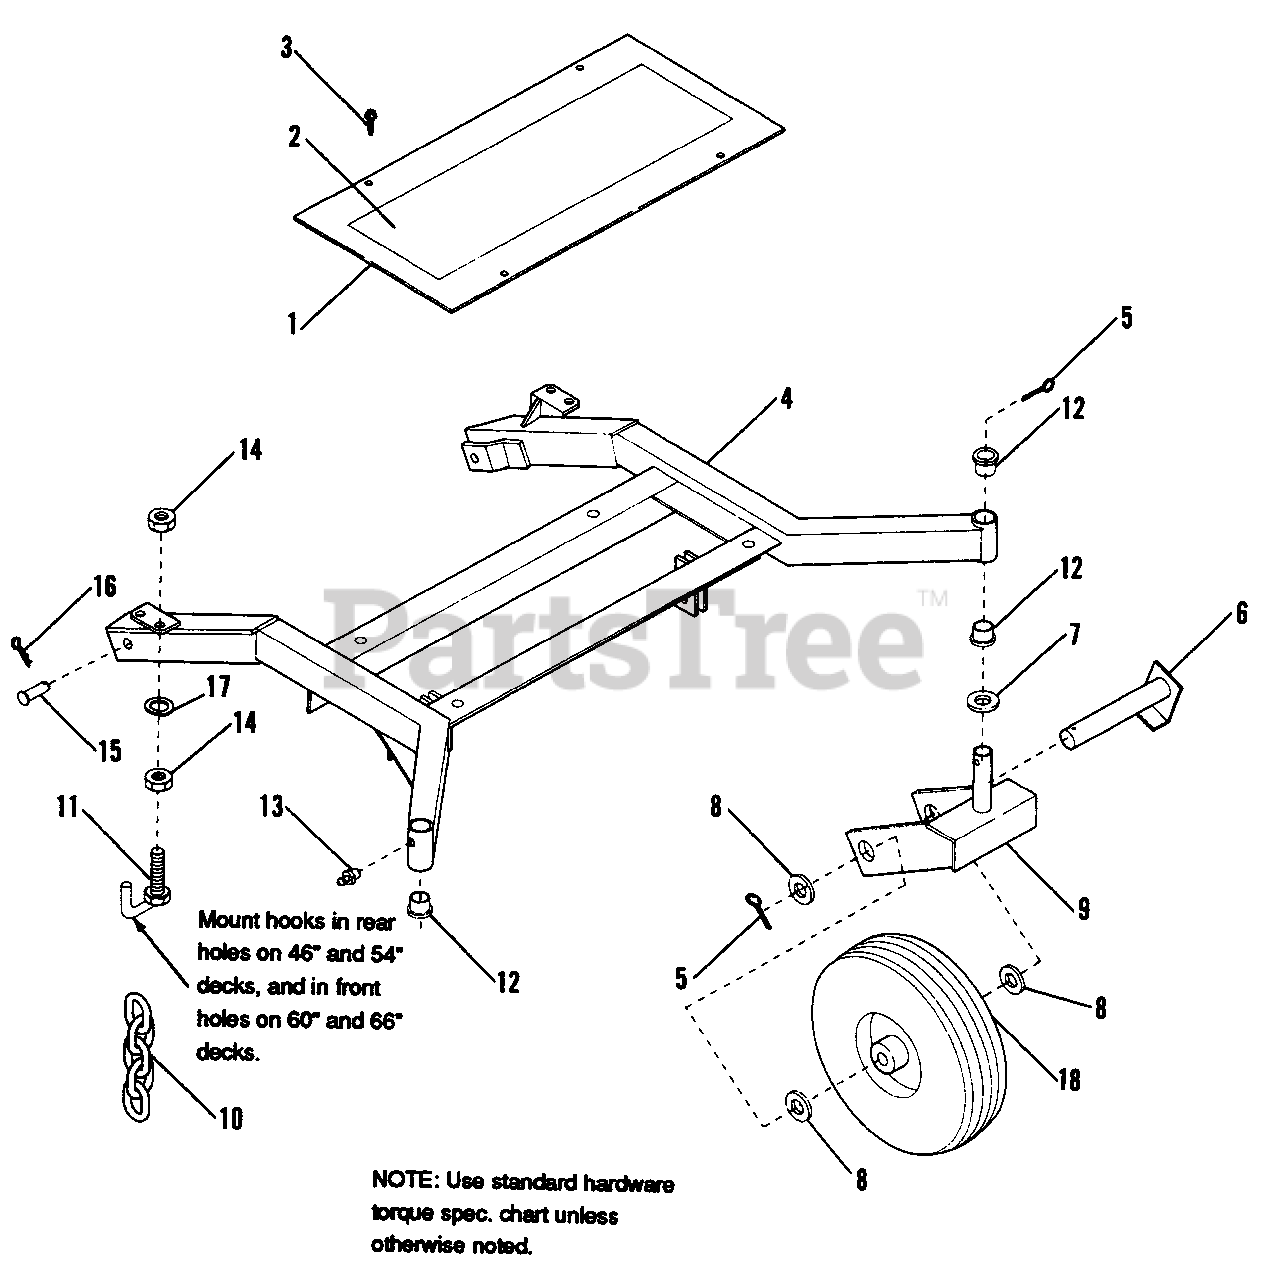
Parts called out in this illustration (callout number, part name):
1	COVER, 46" and 54" (1691847, 1691848)
1	COVER, 60" and 66" (1691849, 1691850)
2	PAD, Non-Skid
3	SCREW, Taptite, 5/16-18 x 1/2
4	MOWER FRAME ASSY. 46" (1691847)
4	MOWER FRAME ASSY. 54" (1691848)
4	MOWER FRAME ASSY. 60" (1691849)
4	MOWER FRAME ASSY. 66" (1691850)
5	COTTER PIN
6	AXLE ASSY.
7	WASHER, Plain
8	WASHER, Plain
9	CASTER ASSY.
10	CHAIN, Lift
12	BEARING, Spindle
13	FITTING, Grease (Press Fit)
14	NUT, Hex 1/2-13
15	CLEVIS PIN
16	COTTER HAIRPIN
17	LOCKWASHER, Spring 1/2
18	TIRE ASSY. 4.10/3.50 x 4
